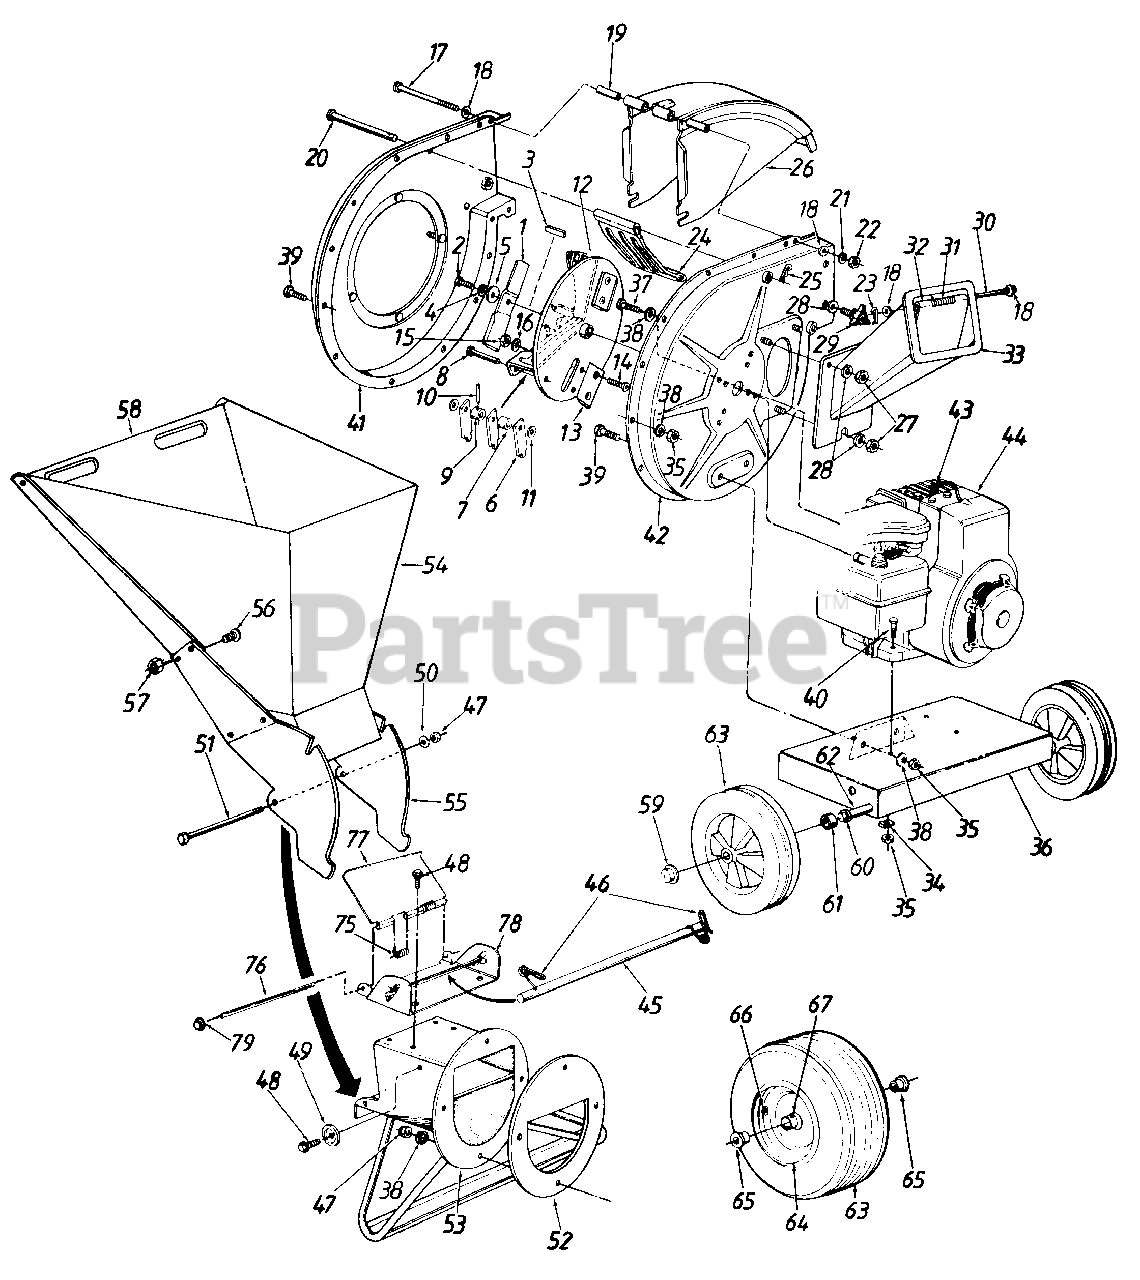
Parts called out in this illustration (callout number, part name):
3	Sq. Key 1/4 x 2.0" Lg.
4	L-Wash. 3/8" 1 .D. H.D.
5	Fl-Wash. .406" I.D. x 1.25" O.D. Hdn.
6	Flail
7	Flail Spacer
8	Clevis Pin .496" Dia.
9	Flail Spacer w/.160" Dia. Hole
10	Spring Roll Pin 1.12" Lg.
11	Fl-Wash. .531" I.D. x .94" O.D.
12	Impeller Ass'y.
13	Chipper Blade
14	Flat Hd. Scr. 5/16-24 x .75" Lg.
15	HexTop L-Nut 5/16-24 (Grade 5)
16	L-Wash. 5/16" I.D.
17	Hex Bolt 1/4-20 x 4.0" Lg.
18	Fl-Wash. .344" I.D. x .875" O.D.
19	Chute Hinge Spacer 1.66" Lg.
20	Clevis Pin .5" Dia. x 4.62" Lg.
21	L-Wash. 1/4" I.D.
22	Hex Nut 1/4-20 Thd.
23	Cotter Pin
25	Internal Cotter Pin 3/8" Dia.
27	Hex Nut 5/16-18 Thd. (Grade 5)
28	Bell-Wash. .345" I.D. x .88"
29	Hand Knob
30	Chipper Door Rod
31	Torsion Spring 1.14" Lg.
35	Hex Nut 5/16-18 Thd. (Grade 5)
36	N/638 Shredder Frame
37	Hex Bolt 5/16-24 x .75" Lg.
38	L-Wash. 5/16" I.D.
39	Hex Bolt 5/16-18 x .75" Lg. (Grade 5)
40	Hex Bolt 5/16-18 x 1.75" Lg.
43	Spark Plug Boot
44	Engine
45	Release Bar
46	Torsion Spring 1.06" Lg.
47	Elastic Lock Nut 5/16-18 Thd.
48	Hex Wash. Hd. Self-Tap Scr. 5/16-18 x .75" Lg.
49	Stop Washer
50	Fl-Wash. 5/16" I.D.
51	Hex Bolt 5/16-18 x 8.38" Lg.
52	Back-Up Plate
53	Inlet Guide Ass'y.
57	Hex L-Nut 1/4-20 Thd.
60	Fl-Wash. .64" I.D. x 1.24"
61	Spacer .64" I.D. x .38" Lg.
62	Shredder Axle
63	Wheel Ass'y. Comp.
64	Rim Only
65	Flange Bearing .632" I.D.
66	AirValve
67	Grease Fitting
75	Torsion Spring
76	Hopper Door Rod
